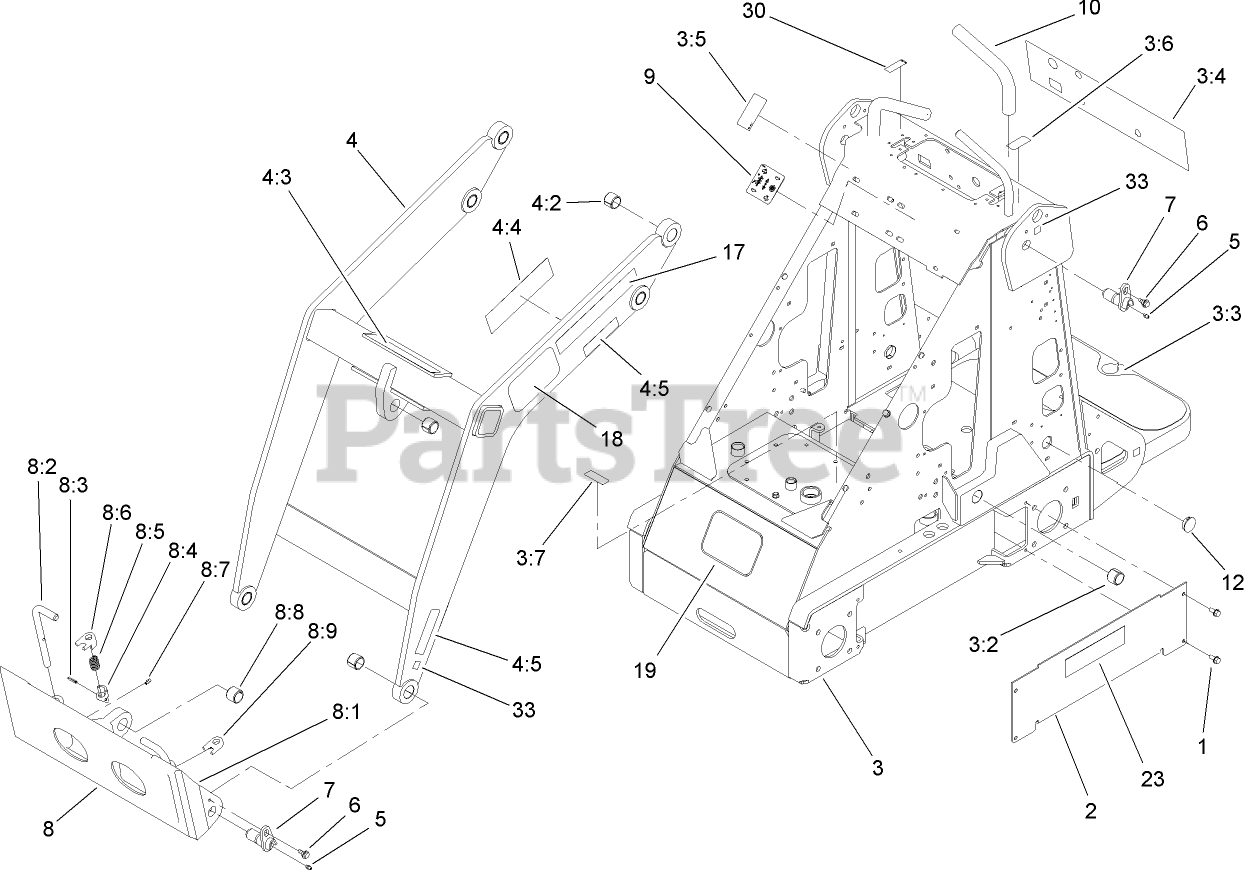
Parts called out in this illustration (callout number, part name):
1	SCREW-HWHTF
2	COVER-HOSE
3	FRAME ASM
3:2	BUSHING-TENSION
3:3	TREAD-FOOT
3:4	DECAL-PANEL, CONTROL
3:5	DECAL-POWER, AUXILIARY
3:6	DECAL-THROTTLE
3:7	DECAL-OIL, HYD
4	LOADER ASM
4:2	BUSHING-TENSION
4:3	DECAL-CAUTION
4:4	DECAL-DANGER
4:5	DECAL-PINCH
5	FITTING-GREASE
6	BOLT-SHOULDER
7	PIN-PIVOT
8	QUICK ATTACH ASM
8:1	MOUNT-ATTACH, QUICK
8:2	PIN-LOCKING
8:3	PIN-GROOVED
8:5	SPRING-COMPRESSION
8:6	STOP-RH
8:7	FITTING-GREASE
8:8	BUSHING-TENSION
8:9	STOP-LH
9	DECAL-SELECTOR, SPEED
10	GRIP-CUSHION
12	PLUG-HOLE
17	Decal
18	DECAL
19	DECAL
30	DECAL-CHOKE
33	DECAL-POINT, LIFT
